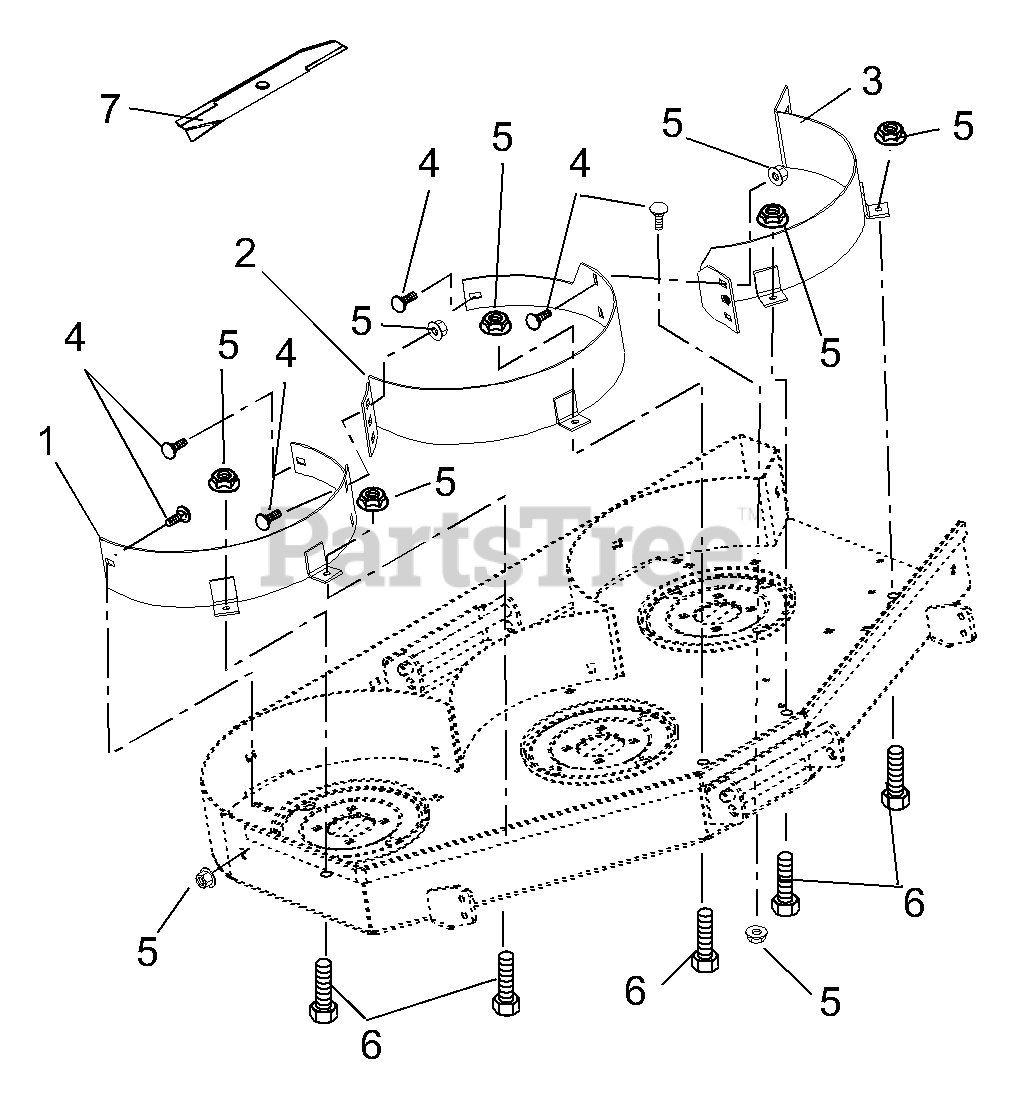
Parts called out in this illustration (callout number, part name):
1	BAFFLE-MULCH-LEFT FRONT-40"
1	MULCHER 40"
1	BAFFLE-MULCH-LEFT FRONT-44"
1	MULCHER 44"
1	BAFFLE-MULCH-LEFT FRONT-48"
1	MULCHER 48"
1	BAFFLE-MULCH-LEFT FRONT-52"
1	MULCHER 52"
2	BAFFLE-MULCH-CENTER FRONT-40"
2	MULCHER 40"
2	BAFFLE-MULCH-CENTER FRONT-44"
2	MULCHER 44"
2	BAFFLE-MULCH-CENTER FRONT-48"
2	MULCHER 48"
2	BAFFLE-MULCH-CENTER FRONT-52"
2	MULCHER 52"
3	BAFFLE-MULCH-RIGHT FRONT-40"
3	MULCHER 40"
3	BAFFLE-MULCH-RIGHT FRONT-44"
3	MULCHER 44"
3	BAFFLE-MULCH-RIGHT FRONT-48"
3	MULCHER 48"
3	BAFFLE-MULCH-RIGHT FRONT-52"
3	MULCHER 52"
4	BLT-RDHDSQSHNK .31-18X.62 BKZC
4	MULCHER 40"
4	MULCHER 44"
4	MULCHER 48"
4	MULCHER 52"
5	NUT-LK-TOP-FLG .31-18 BLKZC
5	MULCHER 40"
5	MULCHER 44"
5	MULCHER 48"
5	MULCHER 52"
6	BLT SERHFWH .31-18X.62 GR5BKZC
6	MULCHER 40"
6	MULCHER 44"
6	MULCHER 48"
6	MULCHER 52"
7	BLADE, MULCH 13.88
7	MULCHER 40"
7	BLADE, MULCH 15.50"
7	MULCHER 44"
7	BLADE, MULCH 16.25
7	MULCHER 48"
7	BLADE, MULCH 18.00"
7	MULCHER 52"
